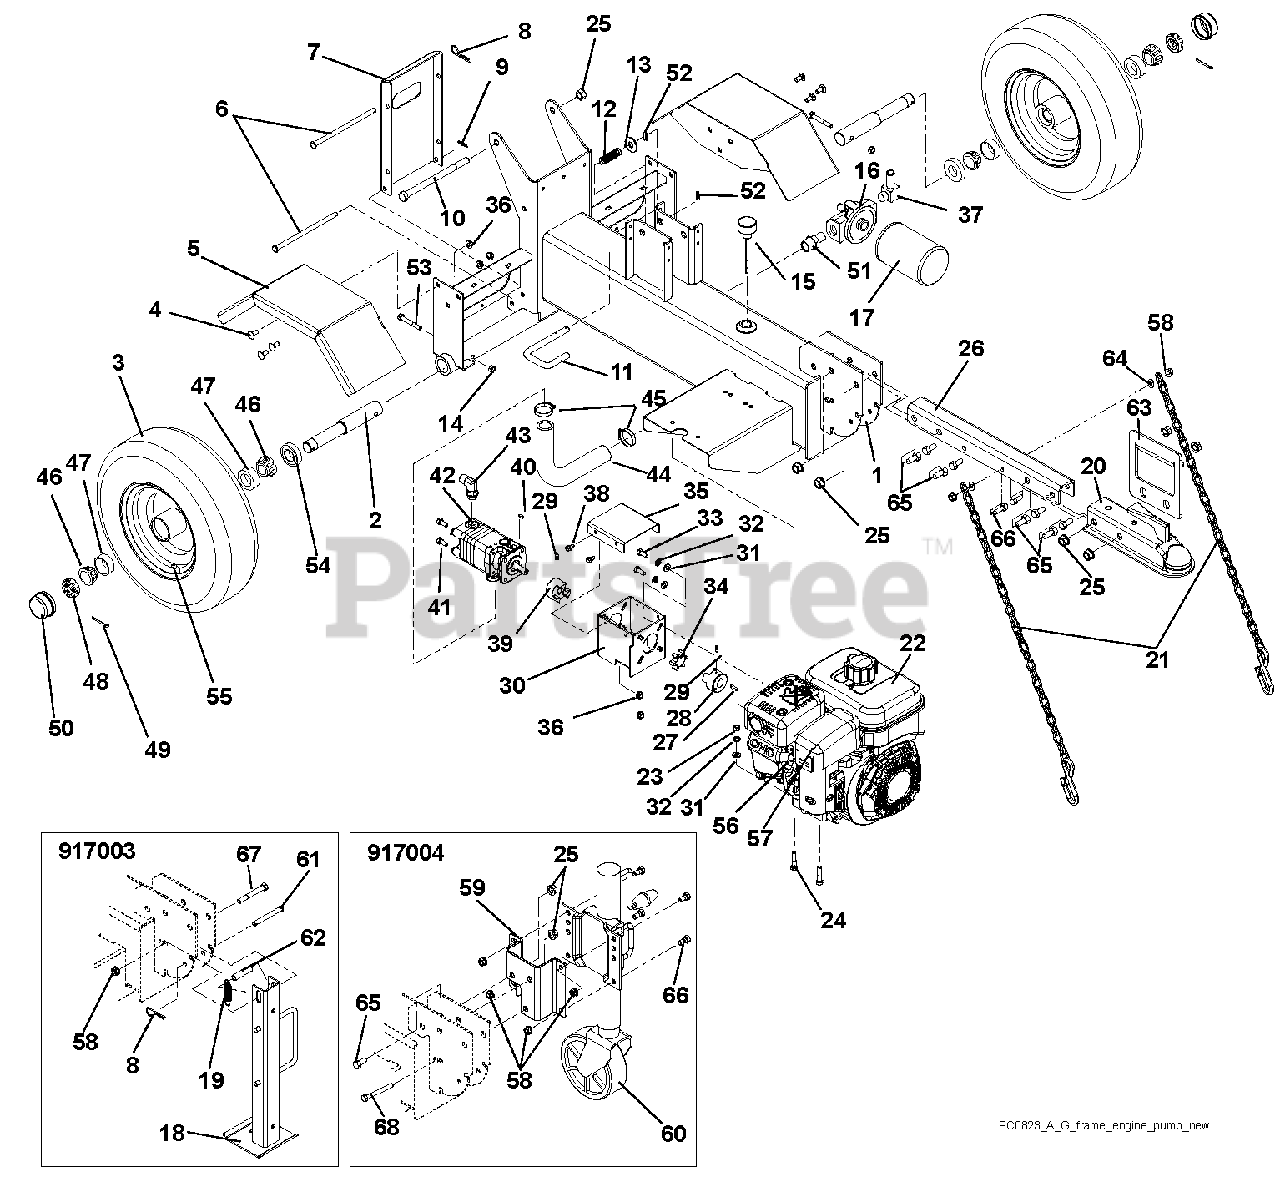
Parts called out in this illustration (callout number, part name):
1	Chassis, Splitter With Safety Decal
2	Axle, Splitter
3	Wheel, Splitter (Includes Items 46, 47, 54 and 55)
4	Bolt, Round Head Square Neck .31-18 x .75
6	Pin, Lock
7	Rear Stand with Decals
8	Hairpin, #7 Clip .094 x .31
9	Pin, Hair #25
10	Bolt, Hex .50-13 x 7.50
11	Lock, Beam
12	Spring, Compression .058 x .65 x 2.13
13	Washer, Flat Steel .563 x 1.38 x .109
14	Nut, Locking Center .31-18
15	Breather, Dipstick
16	Head, Filter 3/4 NPT Bypass
17	Element, Filter
18	Stand, Jack (917003)
19	Spring, Tension .063 x .625 x 2.50 (917003)
20	Hitch, Ball 2-Inch
21	Chain, Safety
22	Engine, Subaru SP170, CARB (917003)
23	Nut, Hex .31-18
24	Bolt, Hex .31-18 x 1.50
25	Nut, Locking Center Flange .50-13 (917003)
26	Bar, Hitch - with Decals
27	Key, Square .188 x .75 x .188
28	Hub, Drive Coupling 3/4 Inch
29	Screw, Set .25-20 x .38 Socket Head Cup Point Nyloc
30	Bracket, Pump Mount
31	Washer, Flat Steel .344 x .688 x .065
32	Washer, Locking .312 x .097 Heavy
33	Bolt, Hex .31-24 x .75
34	Spider, Urethane
35	Cover, With Decals
36	Nut, Locking Top Flange .31-18
37	Fitting, Hydraulic 4501-10-12-FG
38	Screw, Tapping .25-20 x .50 Hex Washer Head Thread Rolling
39	Hub, Drive Coupling 1/2 Inch
40	Key, Woodruff .125 x .50 x .20
41	Bolt, Hex .31-18 x .75
42	Pump, Splitter 11 GPM (917003)
43	Fitting, Hydraulic 6801-8-8
44	Hose, Hydraulic Suction 16G4H x 13.5
45	Clamp, Hose 1.50 x .81 x 1.42
46	Bearing, Cone With Grease
47	Bearing, Cup 1.980 x .420
48	Nut, Slotted 1.0-14
49	Pin, Center .15 x 1.50
50	Cap, Dust
51	Fitting, Hydraulic 5404-12-12
52	Clip, Spring
53	Bolt, Hex .31-18 x 2.25
55	Valve Stem Assembly
56	Spark Plug
57	Filter, Air
58	Nut, Locking Top Flange .38-16 (917003)
59	Bracket, Mounting (917004)
60	Stand, Jack With Wheel (917004)
61	Pin, Clevis .368/.373 x 3.25 (917003)
62	Spacer, Wheel (917003)
64	Washer, Flat Steel .406 x .812 x .065
65	Bolt, Hex .50-13 x 1.00 (917003)
66	Bolt, Hex .38-16 x 1.00 (917003)
67	Bolt, Hex .38-16 x 3.00 (917003)
68	Bolt, Hex .38-16 x 3.25 (917004)
